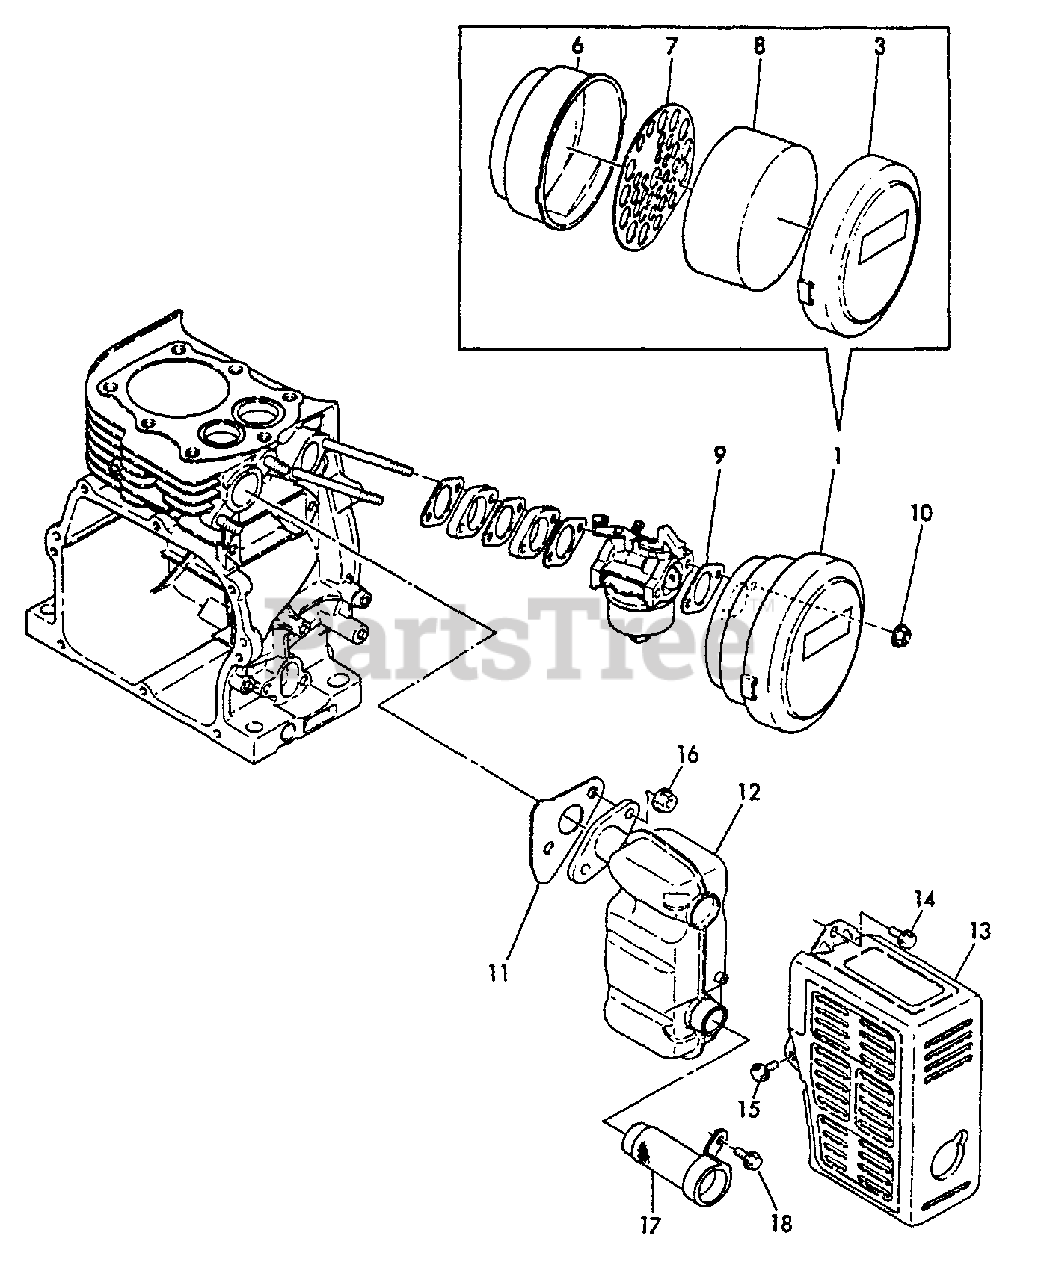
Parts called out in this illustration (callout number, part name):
1	CLEANER ASSY, AIR
3	COVER, AIR FILTER
6	CASE, AIR FILTER
7	PLATE, ELEMENT
8	FILTER, AIR
9	GASKET, INTAKE
10	U-NUT M6
11	GASKET, EXHAUST
12	MUFFLER
13	COVER, MUFFLER
14	BOLT - 6×12 -- PLATED
15	BOLT - 6×8 -- PLATED
16	U-NUT M8
17	SCREEN, SPARK ARRESTER
18	BOLT - 6×10 -- PLATED
